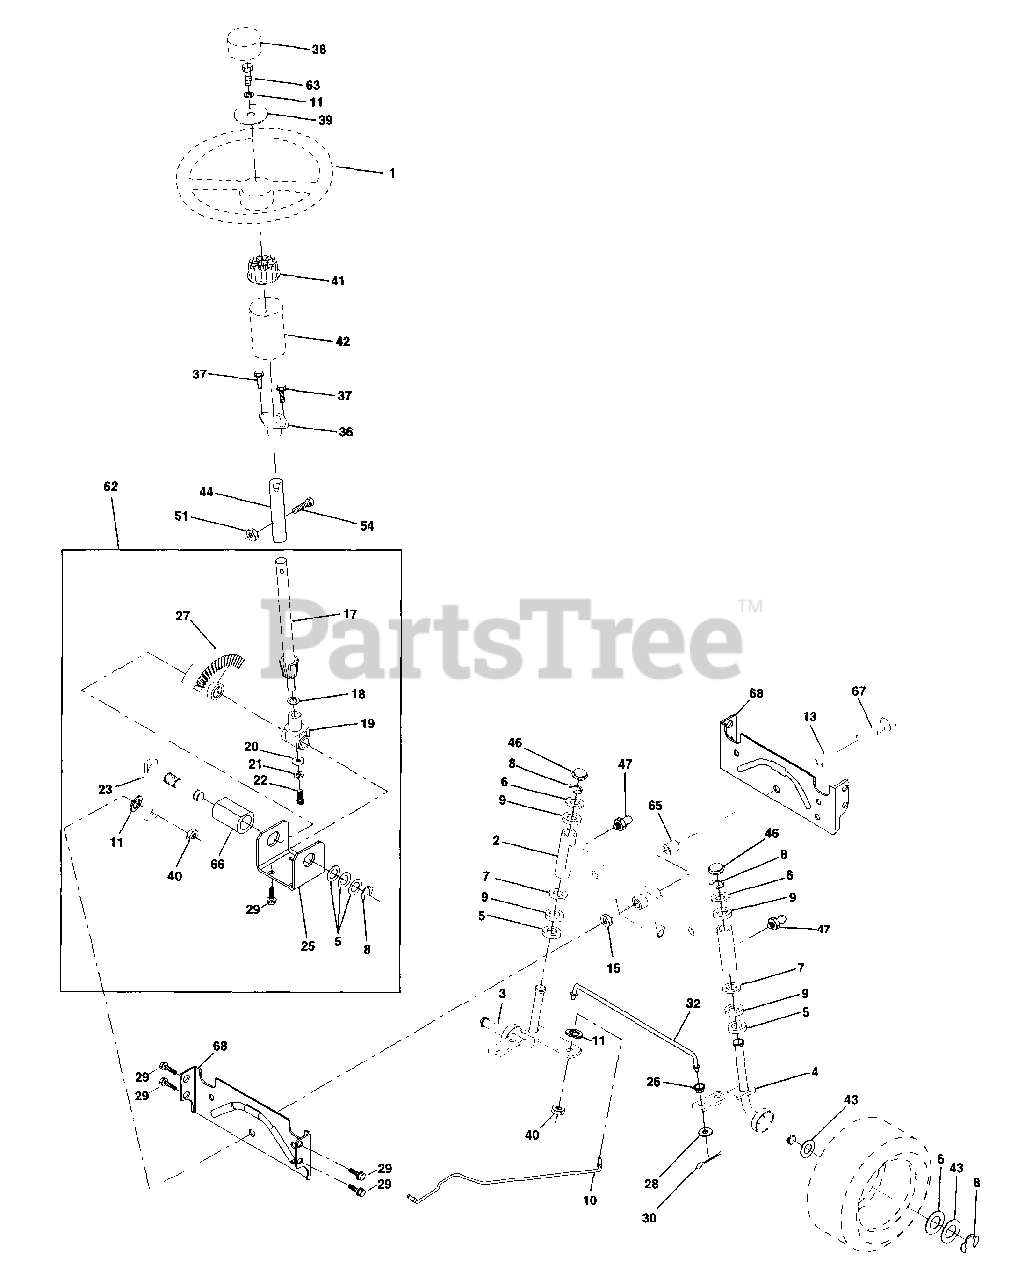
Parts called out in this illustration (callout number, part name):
1	Wheel Steering
2	Axle Asm STMP Dropped STL
3	Spindle Asm LH
4	Spindle Asm RH
5	Bearing Race Thrust Harden
6	Washer 25/32 X 1-5/8 X 16 Ga
7	Washer 27/32 X 1-1/4 X 16 Ga
8	Ring Klip #t5304-75
9	Bearing Col Strg Blk
10	Link Drag Extended Stamp
11	Washer Lock Hvy Hlcl Spr 3/8
13	Bearing Axle STLT/GT
15	Nut Lock Flange 5/8-11 Unc
17	Shaft Asm Strg
18	Washer Thrust 515 x 750 x 033
19	Support Shaft
20	Washer Shim 1/4 X 5/8 X 062
21	Washer Lock Hvy Helical 1/4
22	Screw Cap Sckt Hd Phos & Oil
23	Shaft Asm Pittman
25	Bracket Steering
26	Bushing Link Drag Blk LR
27	Gear Sector
28	Washer 13/32 X 7/8 X 16 Ga
29	Screw Thdrol 3/8-16 x 3/4 Ty-tt
30	Pin Cotter 1/8 X 3/4 Cad
32	Rod Tie Wire Form 19 75 Mech
36	Bushing Strg
38	Insert Cap Strg Wh Au
39	Washer 13/32 X 2-3/8 X 8 Ga
40	Lock nut
41	Adaptor Wheel Strg
42	Boot Steering Shaft
43	Washer 25/32 X 1 1/4 X 16 Ga
44	Extension Steering Shaft LR/LT
46	Cap Spindle Fr Top Blk
47	Fitting Grease
51	Nut Lock Hex w/Ins 5/16-18
54	Bolt Fin Hex 5/16-18 Unc x 1-1/4
62	Kit, Steering Assembly Svc
63	Bolt Fin Hex 3/8-16unc x 1 Gr. 5
65	Spacer Axle
66	Bearing Arm Pittman
67	Bolt, Fin Hex 5/8-11 UNC x 2-3/4
68	Axle, Brace
